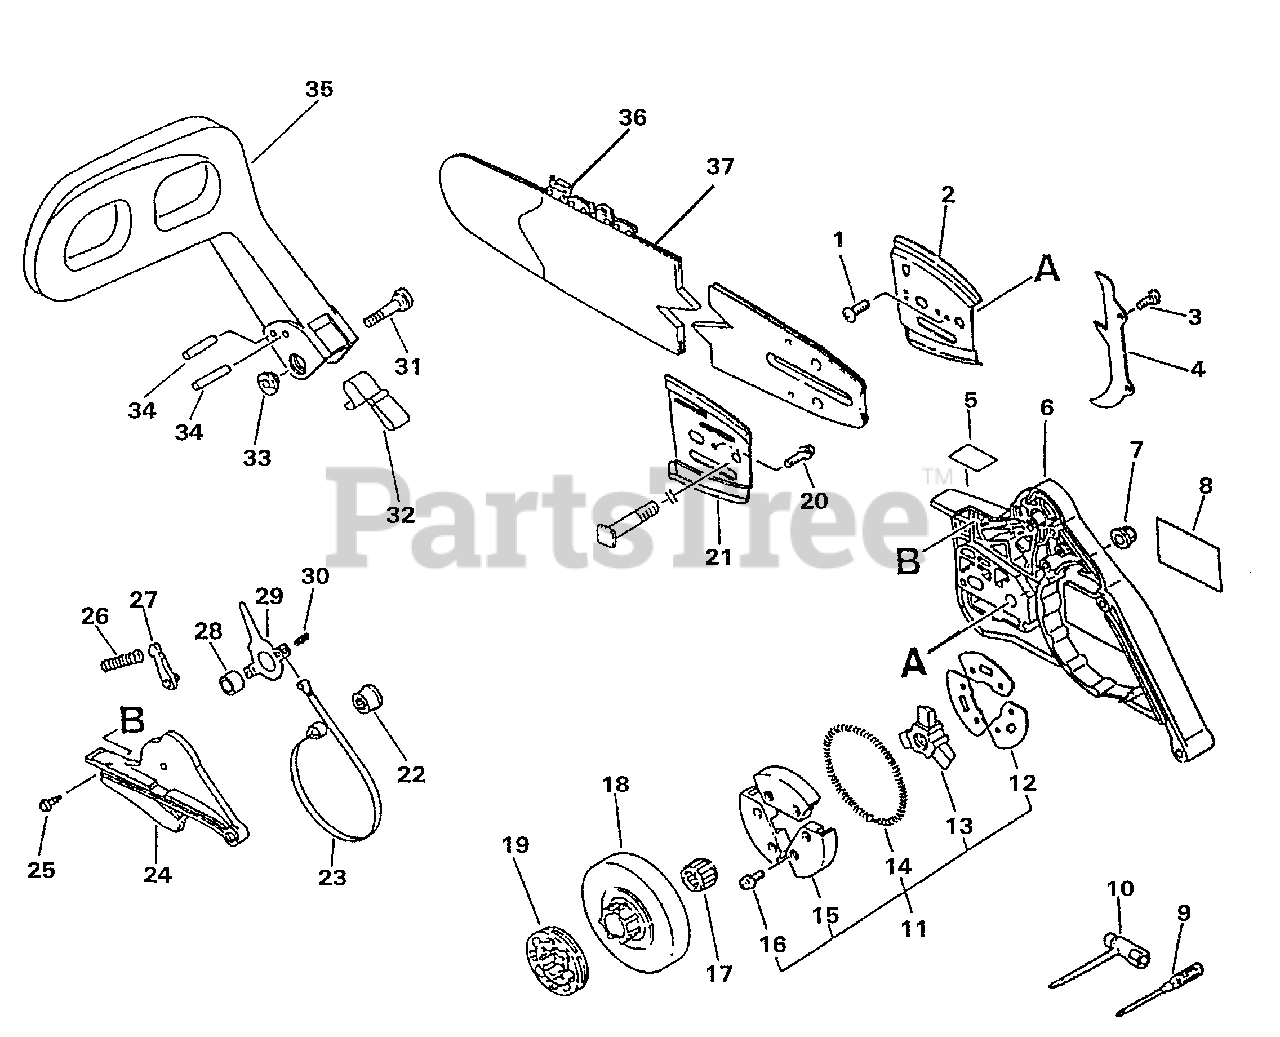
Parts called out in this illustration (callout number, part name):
1	SCREW - 4X8
2	PLATE, GUIDE - OUTER
3	SPIKE KIT
5	LABEL - CAUTION
6	GUARD, SPROCKET
7	NUT - FLANGE
8	LABEL - ECHO
9	SCREWDRIVER
10	T-WRENCH - 13X19mm
11	CLUTCH ASSY
12	PLATE, CLUTCH
13	HUB, CLUTCH
14	SPRING, CLUTCH
15	CLUTCH SHOE SET
16	SCREW - 4X6
17	BEARING, NEEDLE
18	DRUM, CLUTCH
19	SPROCKET, RIM
20	SCREW - 3X6
21	PLATE, GUIDE - INNER
22	ADJUSTER, BRAKE BAND
23	BAND, BRAKE
24	COVER, BRAKE
25	SCREW - 4X10
26	SPRING, BRAKE
27	STOPPER, BRAKE
28	SPACER - 8
29	LEVER, BRAKE
30	PIN - SPRING -- 4X8
31	MOUNTING KIT
32	SPRING, RETURN
34	PIN - 3.5X26
35	LEVER, BRAKE
36	SAW CHAIN - 16" (40cm)
36	SAW CHAIN - 18" (45cm)
36	SAW CHAIN - 20" (50cm)
37	GUIDE BAR - 16" (40cm)
37	GUIDE BAR - 18" (45cm)
37	GUIDE BAR - 20" (50cm)
